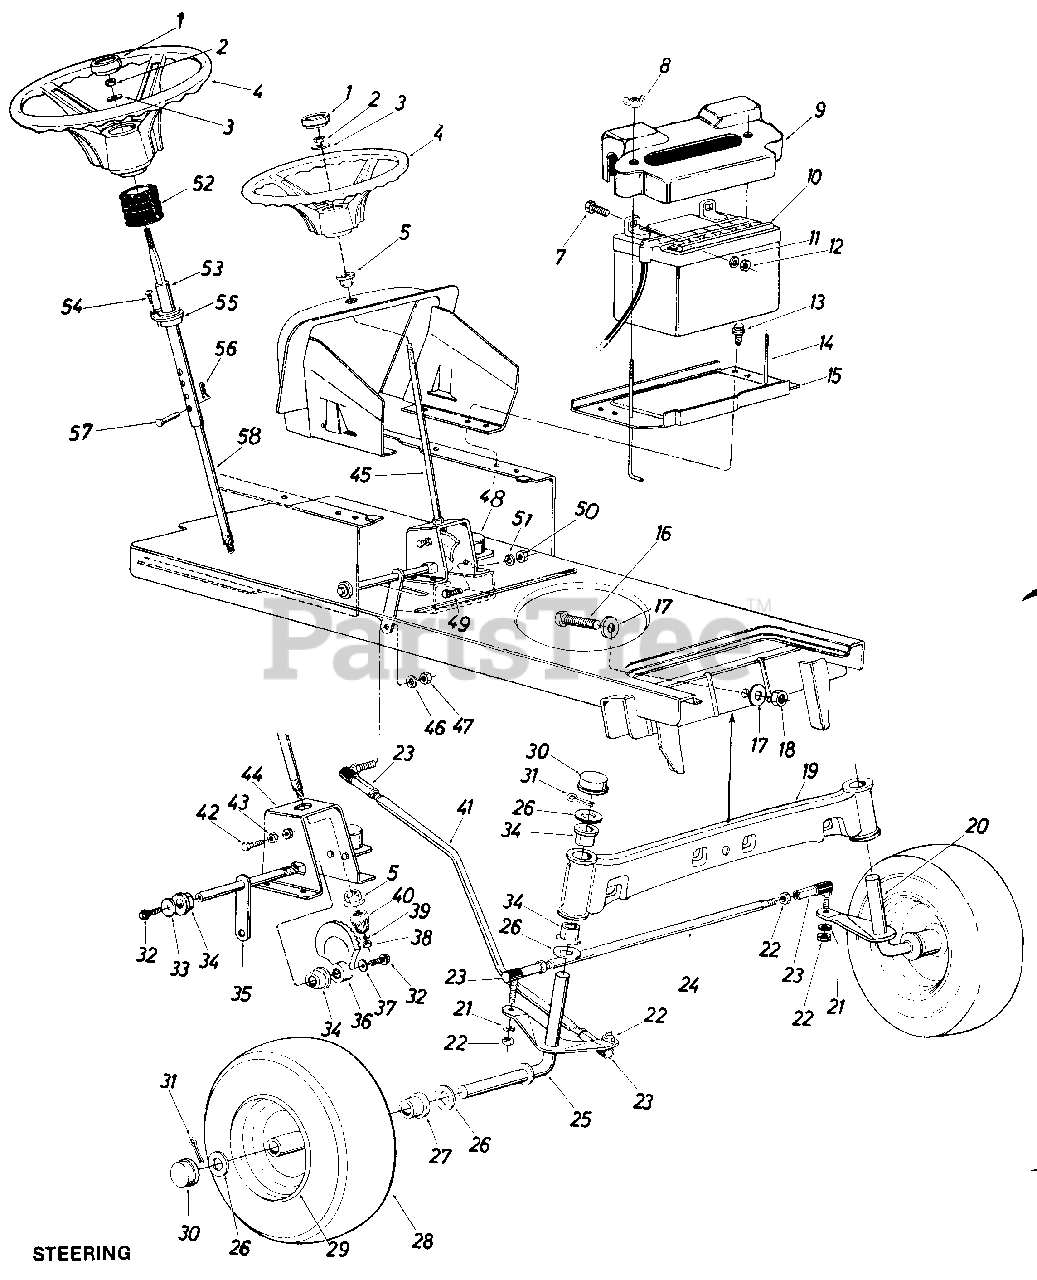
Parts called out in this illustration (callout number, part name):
1	Steering Wheel Cap
2	Hex Cent. L-Nut 5/16-18 Thd.
3	Bell-Wash. 5/16" I.D. x .87" O.D. x .060
4	Steering Wheel
5	Plastic Hex Bearing 5/8" I.D.
7	Hex Scr. 1/4-20 x .62" Lg.
8	Wing Nut Plastic 1/4-20 Thd.
9	Battery Cover
10	12-V Battery
11	L-Wash. 1/4" Scr.
12	Hex Nut 1/4-20 Thd.*
13	Hex Thd. Rolling Scr. 1/4-20 x.50" Lg.
14	Battery Hold Down Rod
15	Battery Plate
16	Hex Scr. 5/8-18 x 2.50" Lg.*
17	Flat Wash. .66" I.D. x 2.25" O.D. x .17
18	Hex Cent. L-Nut 5/8-18 Thd.
19	Front Pivot Bar Ass'y.
20	Front Axle Ass'y.-L.H.
21	L-Wash. 3/8" Scr.
22	Hex Nut 3/8-24 Thd.
23	Ball Joint Ass'y.
24	Tie Rod
25	Front Axle Ass'y.-R.H .
26	Fl-Wash. .780 I.D. x 1.59 O.D.
27	Flange Bearing
28	Front Wheel Ass'y. Comp.
29	Front Wheel Rim Only
30	Dust Cover
31	Cotter Pin 5132" Dia. x 1.00" Lg.*
32	Hex Scr. 3/8-24 x .75" Lg. Grade 5
33	Fl-Wash. 3/8 I.D. x 1.25 O.D. x .090
34	Flange Double "D" Brg. .753 I.D.
35	Steering Arm Shaft Ass'y.
36	Side Gear-Steering
37	Bell-Wash. 3/8" I.D.
38	Hex Cent. L-Nut 5/16-24 Thd.
39	Fl-Wash. 5/16" I.D. x .62 O.D x .059
40	Pinion Gear-Steering
41	Drag Link
42	Hex Nylon Scr. 3/8-16 x 1.25" Lg.
43	Hex Nut 3/8-16 Thd.
44	Steering Gear Sup. Ass'y.
45	Steering Shaft
46	L-Wash. 3/8" Scr.
47	Hex Nut 3/8-24 Thd.
48	Solenoid
49	Hex Scr. 1/4-20 x .62" Lg.
50	Hex Nut 1/4-20 Thd.
51	L-Wash. 1/4" Scr.*
52	Steering Bellow
53	Upper Steering Shaft
54	Oval Hd. Cr.-Sunk Scr. #10 x 518" Lg.
55	Fl-Bearing .89" I.D. x 1.36" O.D.
56	Hairpin Cotter
57	Clevis Pin
58	Lower Steering Shaft
